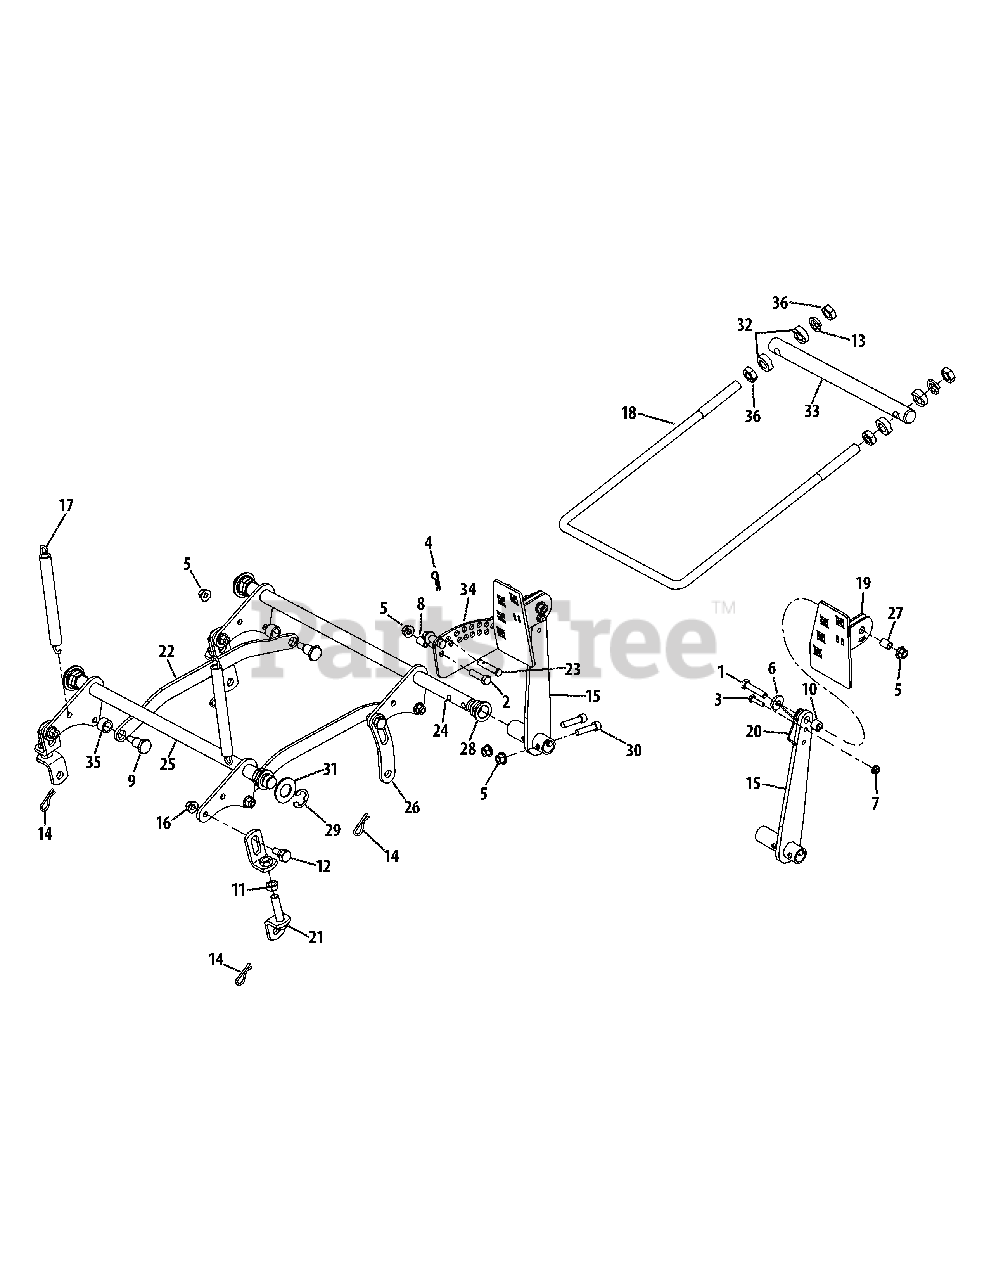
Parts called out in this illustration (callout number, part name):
1	Hex Screw, 3.8-16 x 1.75
2	Hex Screw, 3.8-16 x 1.50
3	Hex Screw, 1.4-20 x 1.00
4	Hair Pin, 3.8 x 1.562 x .080
5	Flange Counterlock Nut, 3.8-16
6	Washer, .390 x 1.00 x .180
7	Flange Toplock Nut, 1.4-20
8	Spacer, .375 x .500 x .750
9	Shoulder Bolt, 3.8-16 x .625 x .830
10	Spacer, .385 x .625 x .500
11	Jam Nut, 1.2-20
12	Shoulder Bolt, 3.8-16 x .56 x .27
13	Lock Washer, .633 x 1.07 x .161
14	Hair Pin, 1.2 x 1.625 x .125
16	Adjustable Deck Lift Bracket
17	Extension Spring, .75 x 7.89 x .14
18	Front Lift Rod
19	Foot Pedal Assembly
20	Torsion Spring, .900 x 2.3 x .09
21	Lower Bracket Assembly
22	Lift Connecting Link
23	Clevis Pin, 3.8 x 2.05
24	Front Shaft Assembly
25	Rear Shaft Assembly
26	Curved Link Plate
27	Spacer, .380 x .500 x .667
28	Hex Flange Bearing, 7.8
29	Retaining Clip, .675
30	Sockt Cap Screw, 3.8-16 x 1.50
31	Washer, .940 x 1.75 x .110
32	Spacer, .635 x 1.2 x .41
33	Trailing Link Pivot Rod
35	Spacer, 632 x .877 x .548
36	Jam Nut, 5.8-11
